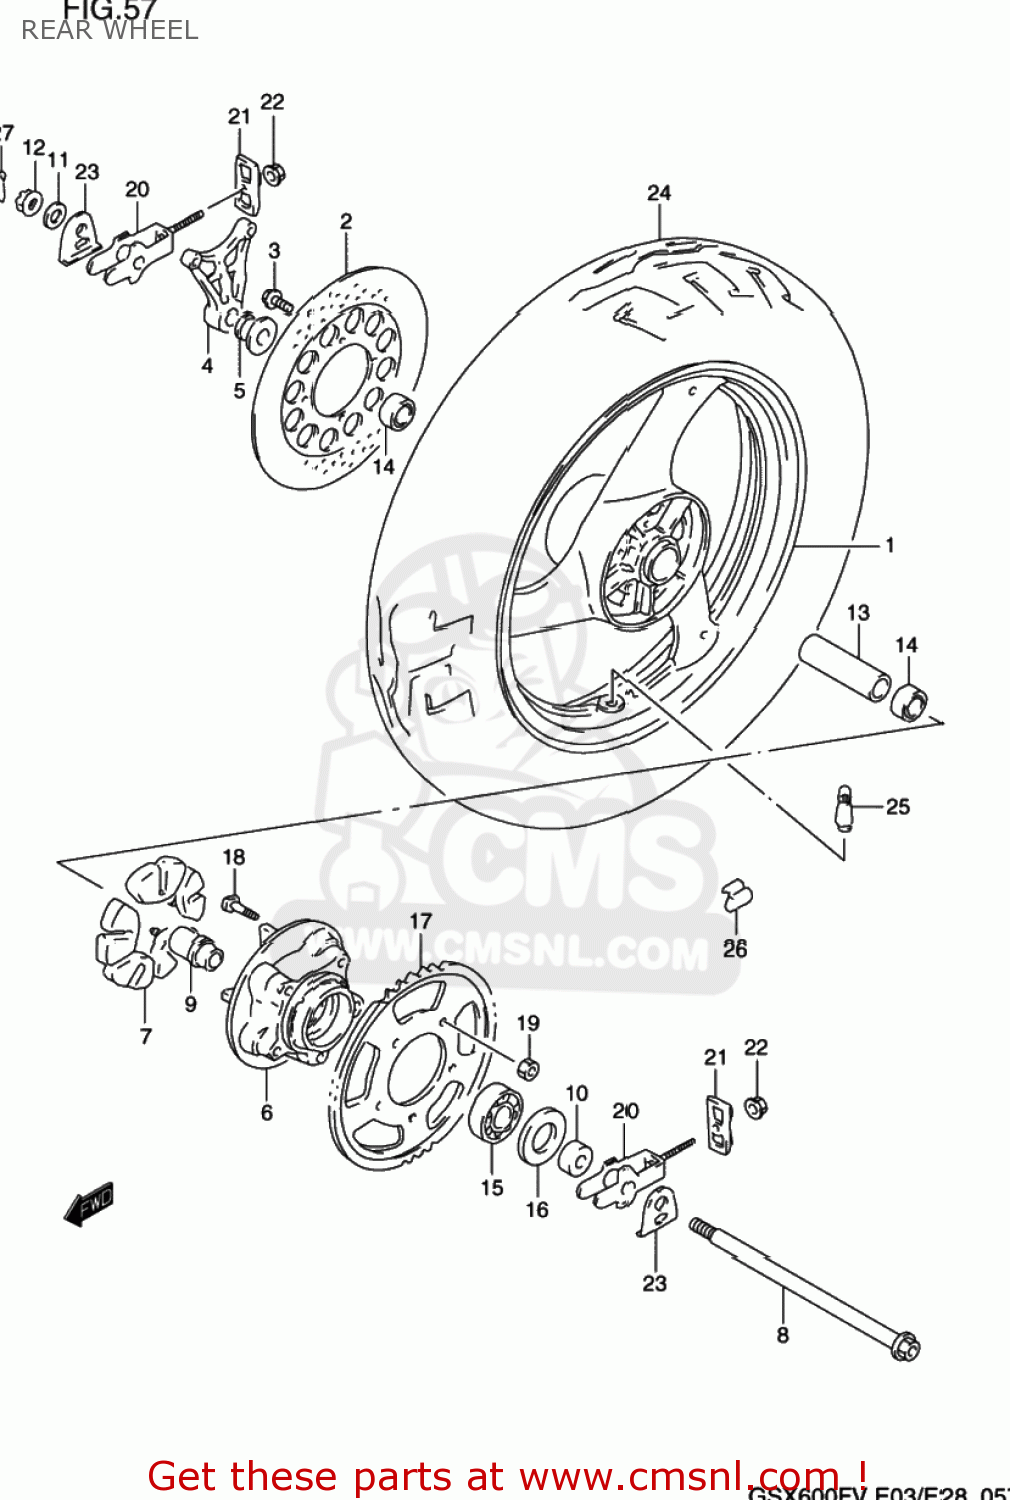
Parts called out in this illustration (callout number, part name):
1	WHEEL,REAR (MT3.50X17)
2	DISC,RR BRAKE
3	BOLT(8X30)
4	BRACKET,RR,CALIPER
5	SPACER,RR AXLE,R
6	DRUM,RR SPROCKET MOUNTING
7	ABSORBER,RR HUB SHOCK
8	AXLE,REAR
9	RETAINER,RR SPROCKET DRUM
10	SPACER,RR AXLE,L
11	WASHER (17X30X3.2)
12	NUT
13	SPACER(17.5X25X88)
14	BEARING
15	BEARING(25X62X17)
16	SEAL,OIL(35X62X8)
17	SPROCKET,RR(NT:45-530)
18	BOLT(10X47)
19	NUT
20	ADJUSTER,CHAIN
21	PLATE,CHAIN ADJUSTER GUIDE
22	NUT
23	WASHER,CHAIN ADJUSTER
24	TIRE,RR(140/80-17 69V)
25	VALVE ASSEMBLY,WHEEL,TR412
26	BALANCER,WHEEL (10G)
27	PIN,COTTER
